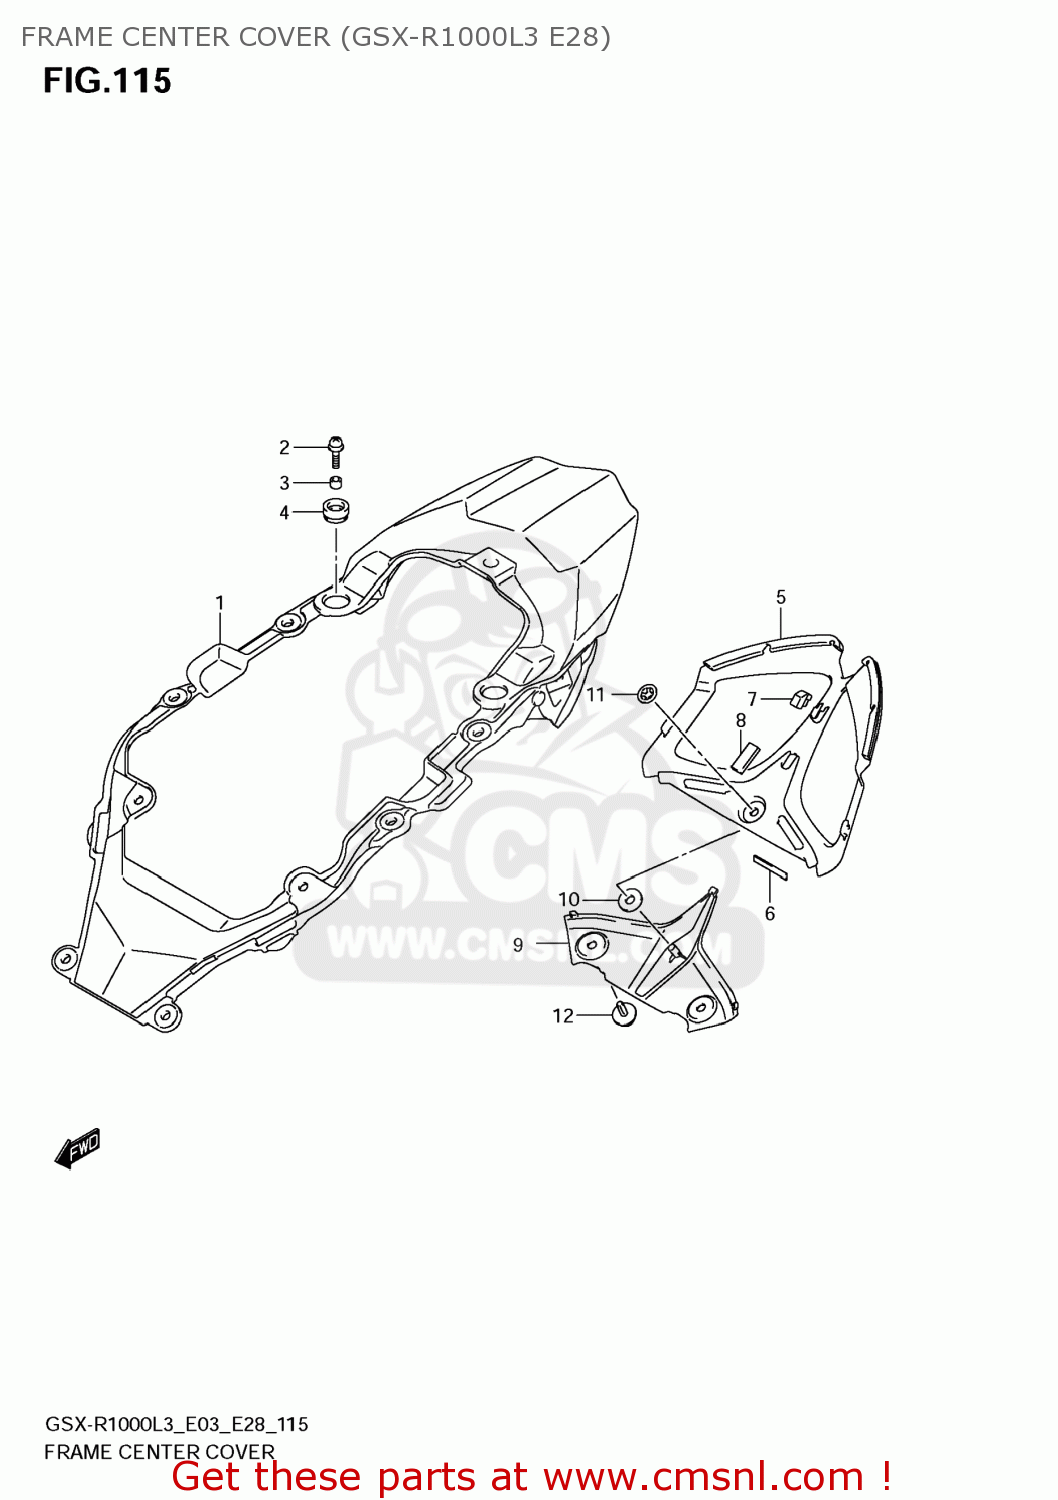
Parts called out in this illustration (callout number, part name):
1	COVER,FRAME CTR
2	SCREW(6X16)
3	SPACER(6.5X10X7)
4	CUSHION,FRAME COVER RR
5	COVER,FRAME RR CTR
6	CUSHION,FRAME COVER RR CTR
7	CUSHION,FRAME COVER RR CTR
8	CUSHION,CTR PANEL UPR
9	COVER,FRAME RR CTR LWR
10	CUSHION
11	NUT
12	CLIP
